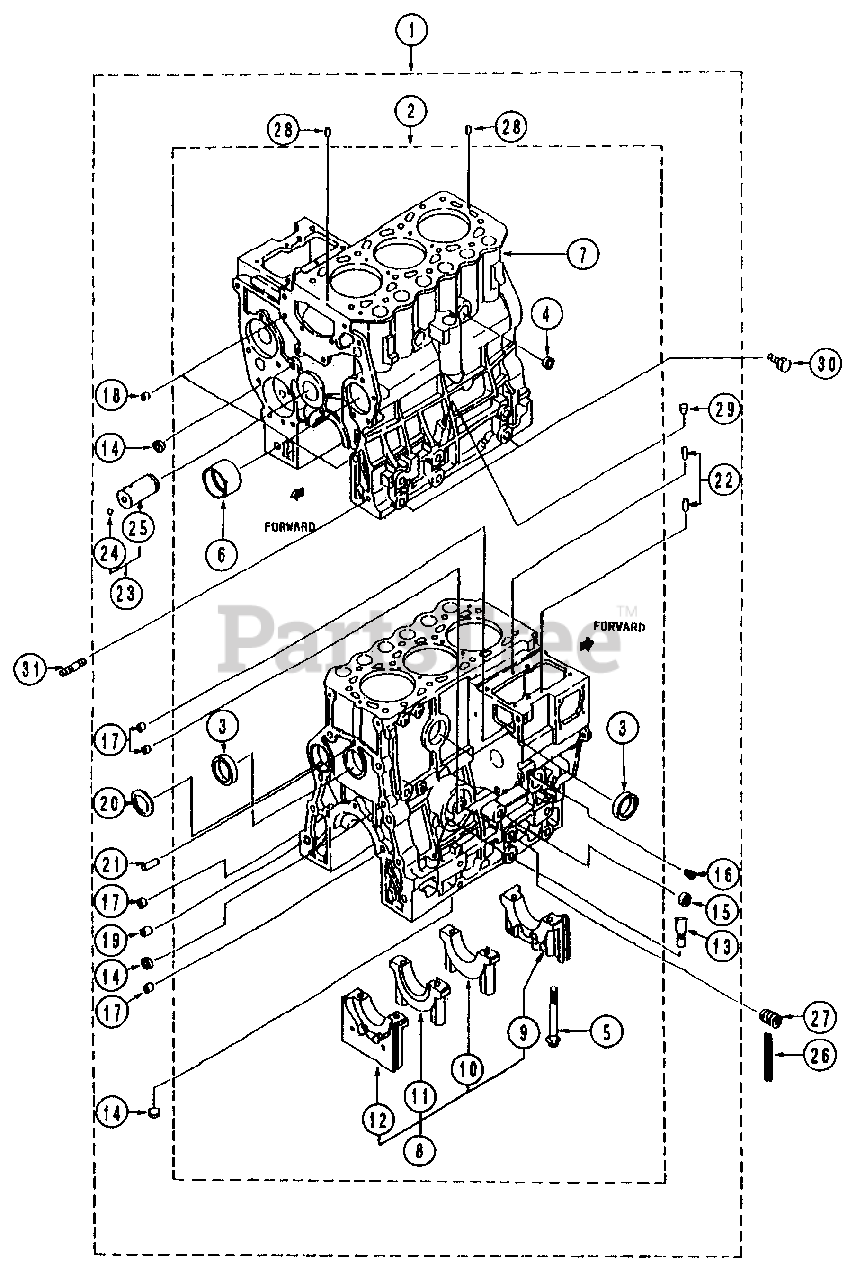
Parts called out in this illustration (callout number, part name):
1	Block Ass'y., Cylinder
2	Block Sub Ass'y., Cylinder
3	Cap, Sealing
4	Cap, Sealing
5	Bolt, Bearing Cap
6	Bush, Camshaft
7	Block, Cylinder
8	Cap Set, Metal
9	Cap, Metal Front
12	Cap, Metal Rear
13	Retainer, Oil Level
14	Cap, Sealing (12)
15	Cap, Sealing
16	Plug, Taper
17	Bushing, Knock
18	Bushing, Knock
19	Bushing, Knock
20	Plug, Expansion
23	Shaft Ass'y., Idler
25	Shaft, Idler
27	Shaft, Oil Filter
29	Plug, Taper
